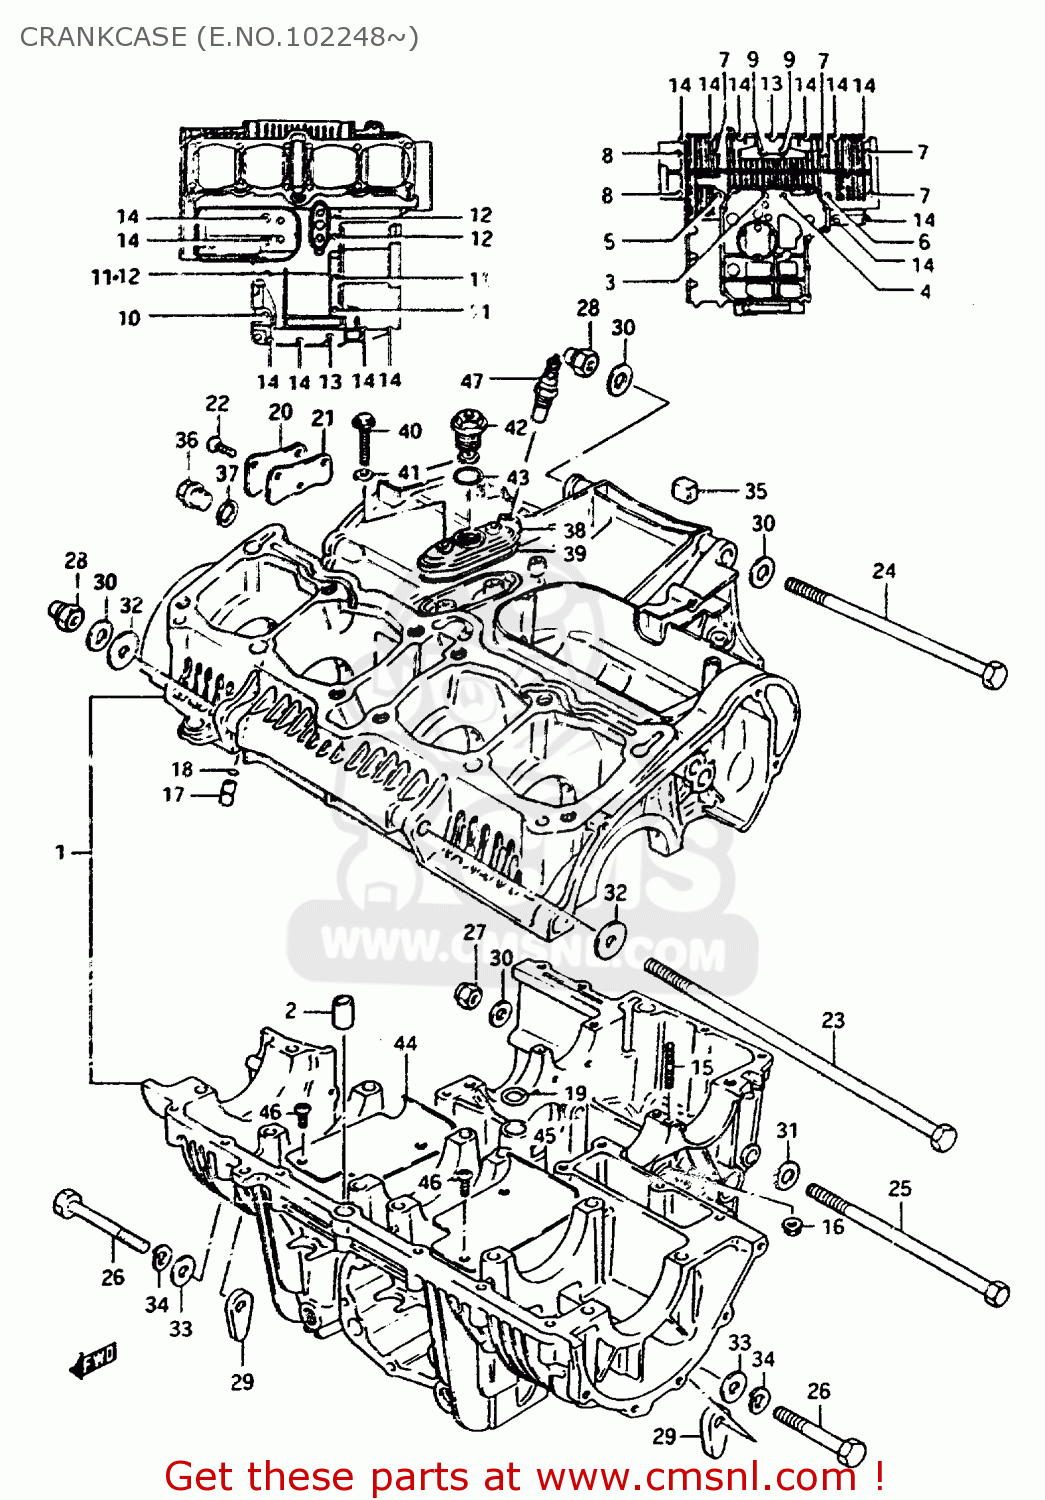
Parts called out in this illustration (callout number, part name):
1	CRANKCASE SET
2	PIN
3	BOLT(9X180)
4	BOLT(9X135)
5	BOLT(8X115)
6	BOLT(8X100)
7	BOLT 8X90
8	BOLT(8X65)
9	BOLT(9X60)
10	BOLT 8X60
11	BOLT
12	BOLT (6X75)
13	BOLT 6X55
14	BOLT
15	STUD 6X50
16	NUT
17	UNION
18	O RING(D:1.05,ID:3.1)
19	O RING(D:3.2,ID:12.9)
20	CAP,OIL GALLERY
21	GASKET,OIL GALLERY (MCA)
22	SCREW
23	BOLT
24	BOLT 10X180
25	BOLT(10X165)
26	BOLT 10X60
27	NUT (10MM)
28	NUT
29	NUT
30	WASHER
31	WASHER
32	WASHER
33	WASHER (10.5X20X3.2)
34	LOCK WASHER
35	PAD,CYLINDER
36	PLUG (14X12)
37	GASKET(14X19.2X2) (NAS)
38	HOUSING,OIL PRESSURE SWITCH
39	O RING,PRESSURE SWITCH HOUSING
40	BOLT
41	WASHER
42	SWITCH ASSEMBLY
43	O RING(D:1.9,ID:18.8)
44	PLATE,OIL SEPARATOR
45	PLATE,OIL SEPARATOR
46	SCREW
47	GAUGE ASSEMBLY,OIL TEMPERATURE
